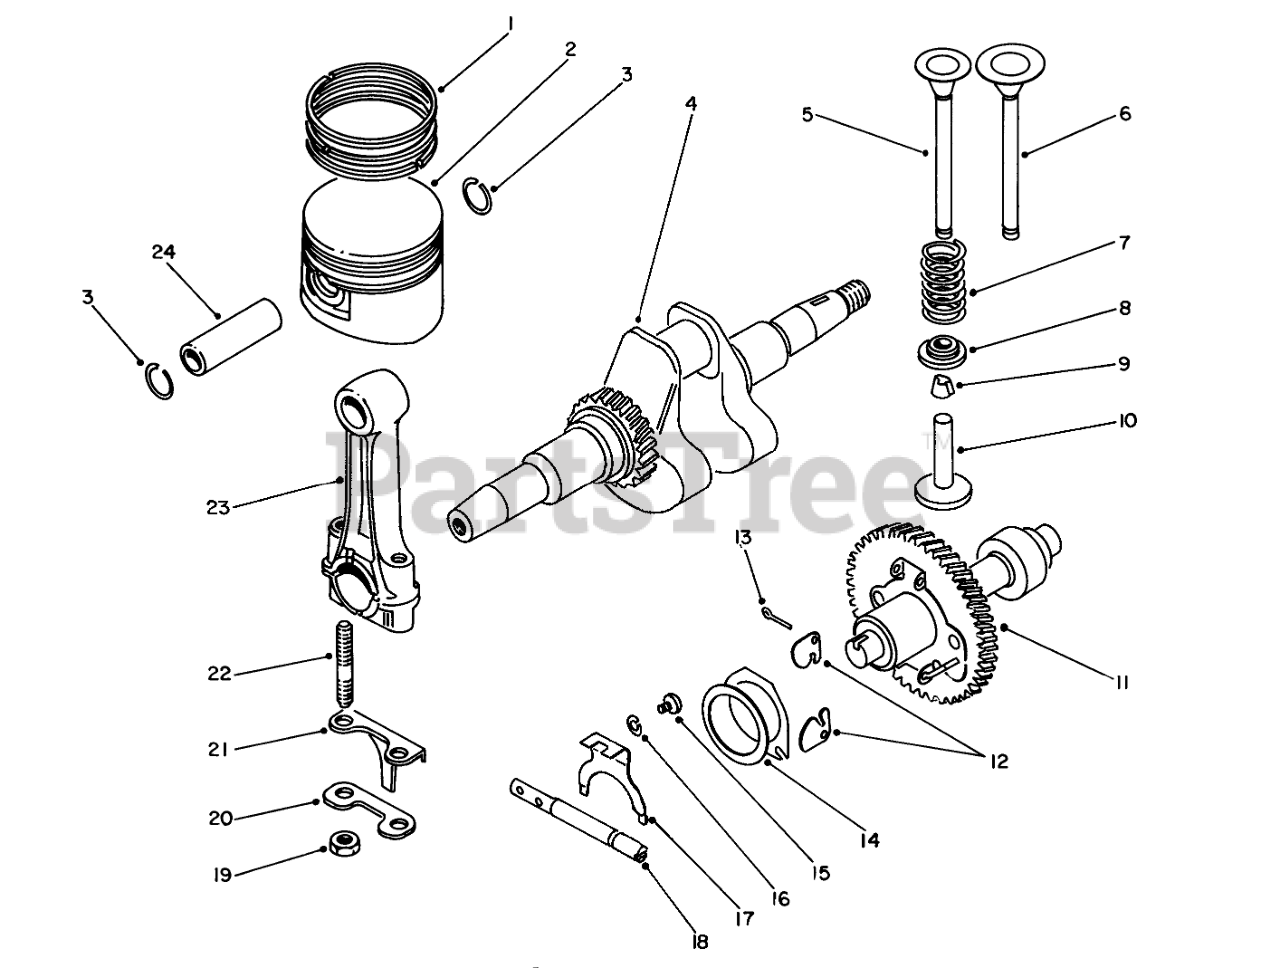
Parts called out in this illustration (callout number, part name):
1	Ring Set-Piston Std.
2	Piston Std.
3	CIRCLIP
4	Crankshaft
5	Valve-Exhaust
6	Valve-Intake
7	Spring-Valve
8	Retainer
9	Cotter
10	Tappet (L:36.46)
11	Cam Shaft
13	Cotter Pin
14	Spacer
15	SCREW
16	Washer
17	Plate-Shift
18	Shaft-Throttle Return
20	LOCK PLATE
21	PLATE
22	Stud Bolt
23	Rod-Connecting (Std.)(Incl. Ref. #19-22)
24	PISTON PIN
